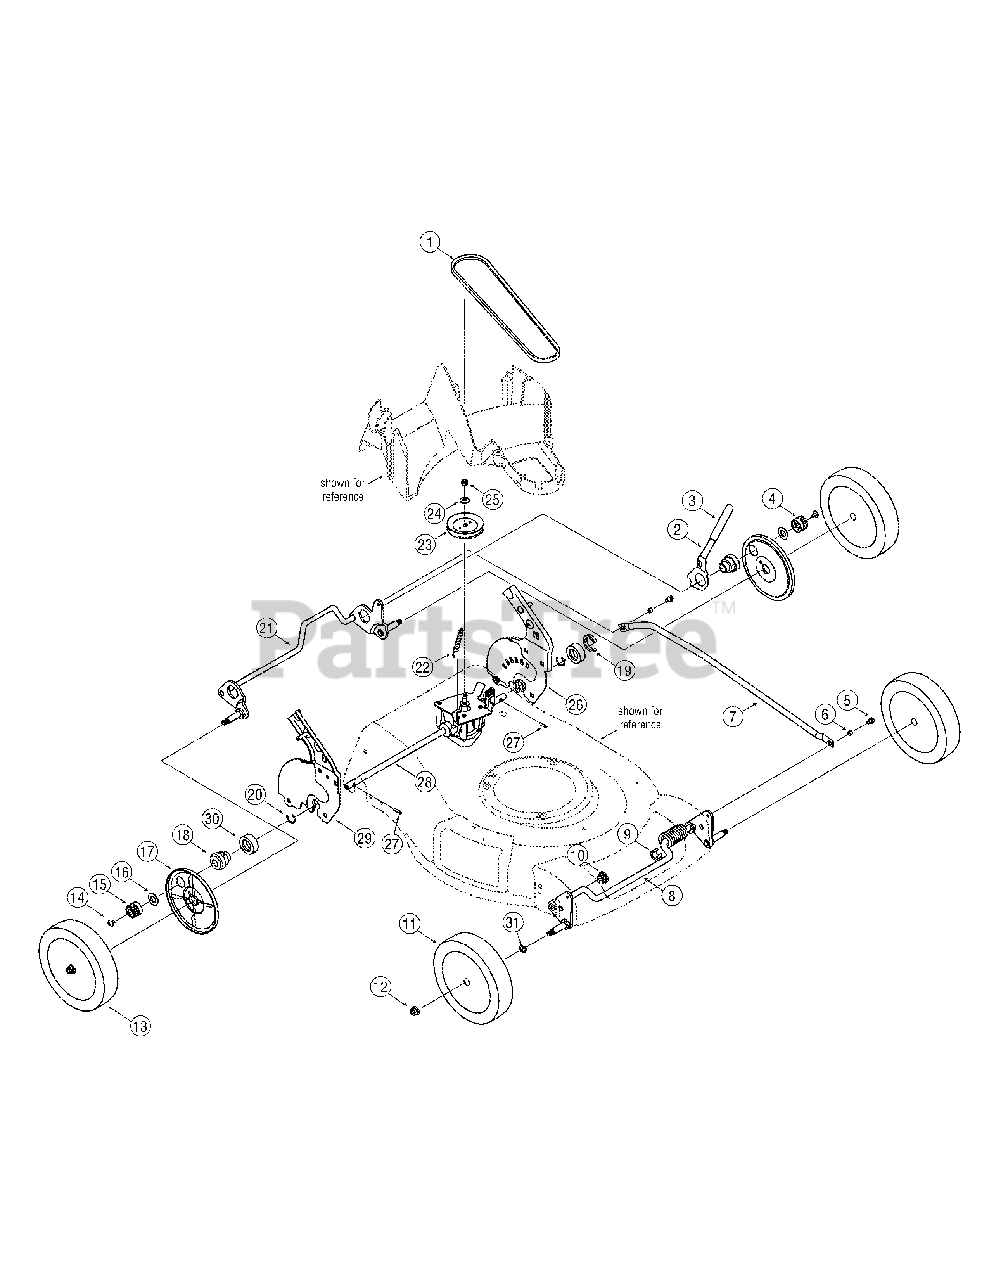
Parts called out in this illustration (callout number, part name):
1	V-Belt
2	Spring Lever
3	Foam Grip
4	Spur Gear, 14T - LH
5	TT Screw, 1/4-20 x 0.50
6	Spacer
7	Cross Bracket
9	Clip Spacer
10	Split Hex Flange Bearing
11	Front Wheel
12	Flange Lock Nut, 3/8-16
13	Rear Wheel
14	Screw, 1/4-20 x .39
15	Spur Gear, 14T - RH
16	Flat Washer
17	Wheel Dust Cover
18	Transmission Bearing Support
19	Clip Spacer
20	Retaining Ring .875
21	Rear Bracket Assembly
22	Extension Spring
23	Pulley, 3.36 OD
24	Bell Washer, .375 x .870 x .063
25	Hex Lock Nut, 5/16-16
26	Handle Bracket Assembly LH
27	Dowel Pin
28	Transmission Assembly
30	Bearing Support Spacer
31	Washer, Wave, .510 x .750 x .017
